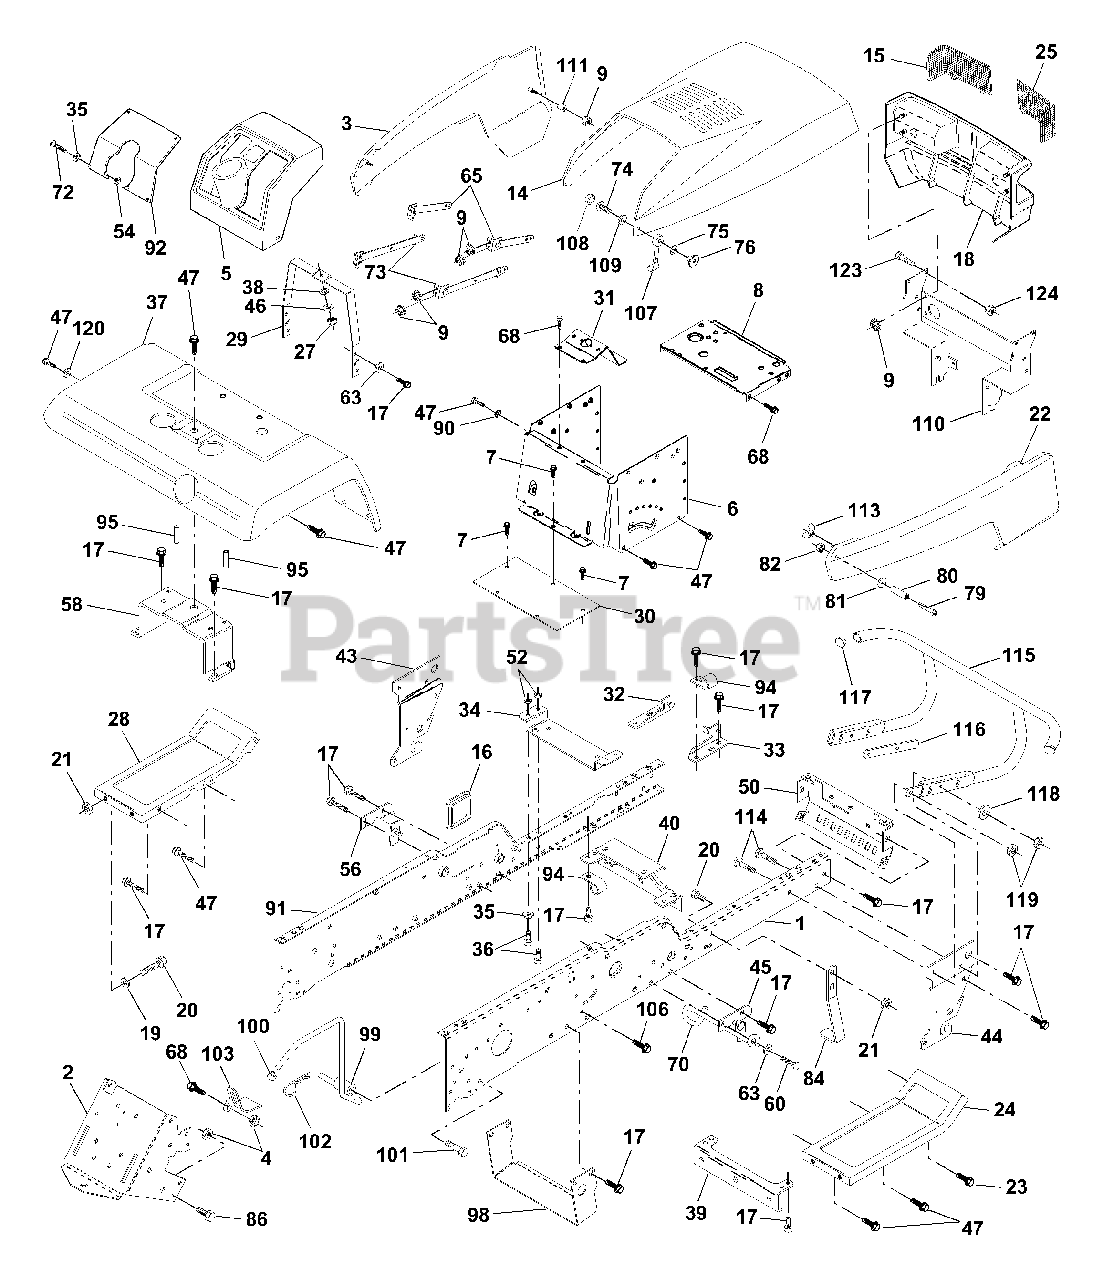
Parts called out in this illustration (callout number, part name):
1	Rail, Frame RH
2	Drawbar, Gt
3	Panel Asm., Side LH
4	Nut, Lock Hex 7/16 Unc
5	Dash, Plastic Black
6	Dash 1-PCS, Lower
7	Screw, Thd Cut 1/4-20 x 1/2
8	Support, Battery
14	Hood Asm., Pnt
15	Lens, Headlight RH
16	Cover, Access
17	Screw, Thdrol 3/8-16 x 3/4
18	Grille
19	Washer 13/32 x 13/16 x 12 Ga.
20	Bolt, Fin Hex 3/8-16 x 1
21	Nut, Lock Hex W/Wsh 3/8-16 Unc
22	Panel Asm., Side RH
24	Footrest, RH
25	Lens Headlight LH
27	Nut Fin Hex 1/4-20
28	Footrest, LH
29	Bracket, Support Dash
31	Brace, Support Steering
32	Bracket Asm., Frame Pivot Lh
33	Bracket Asm., Frame Pivot Rh
34	Bracket, Engine Support Rear
35	Washer 11/32 x 11/16 x 16 Ga.
36	Bolt, Fin Hex 5/16-18 x 3/4
37	Fender, Pnt.
38	Washer, Lock 1/4
39	Bracket, Axle Front
40	Bracket, Support Axle/Engine
43	Bracket, Spnsn Front Lh
44	Bracket, Spnsn Front Rh
45	Bracket Asm., Susp Chassis Rh
46	Washer 9/32 x 3/4 x 16 Ga.
47	Screw Thdrol 3/8-16 x 1/2
50	Bracket, Chassis Front
52	Locknut, Hex W/Ins 5/16-18 Unc
54	Nut 5/16-18
56	Bracket Asm., Susp Chassis Lh
58	Bracket Asm., Fender
60	Screw Thdrol 3/8-16 x 1-1/4
63	Washer 13/32 x 1 x 14 Ga.
65	Strap, Asm. Hinge Front
68	Screw, Thdrol 5/16-18 x 1/2
70	Guide, Belt Mid Span
72	Screw, Mach Trhd 5/16-18 x 3/4
73	Strap, Asm. Hinge Rear
74	Screw, Machine #10-24
75	Washer, Lock #10
76	Nut, Weld #10-24
79	Screw, Machine #10-24 x 1/4
80	Spacer, Split
81	Washer 7/32 x 1/2 x 18 Ga.
82	Nut #10-24
84	Stop, Over Center 44" 20/23" T. 94
86	Bolt, Fin Hex 7/16-14 Unc x 1
90	Washer, Lock External Tooth 3/8
91	Rail, Frame Lh
92	Plate, Silkscreen Dash
94	Clip, Fuel Line
95	Push Nut, Nylon
98	Bracket Chassis Skid
99	Rod Asm. Bypass
100	Cap Brake Parking Red
101	Screw Thdrol. 3/8-16 x 1-3/4
102	Retainer Spring 1"
103	Bracket Lock Bypass
106	Screw Thdrol. Hex Hd Zinc Mur
107	Latch, Chute Blk
108	Cap, Snap Black
109	Cap, Washer Snap
110	Support Asm. Grille
113	Nut, Plastic Locking Wing 1/4-20
114	Bolt, Carriage 3/8-16 x 1-1/4
115	Bumper Asm.
116	Bracket Extension Bumper
117	Plug Plastic
118	Washer 13/32 x 13/16 x 16 Ga.
119	Nut Crownlock 3/8-16 UNC
120	Washer 13/32 x 1 x 16 Ga.
123	Bolt Shoulder 1/4-20
124	Nut Crownlock 1/4-20
